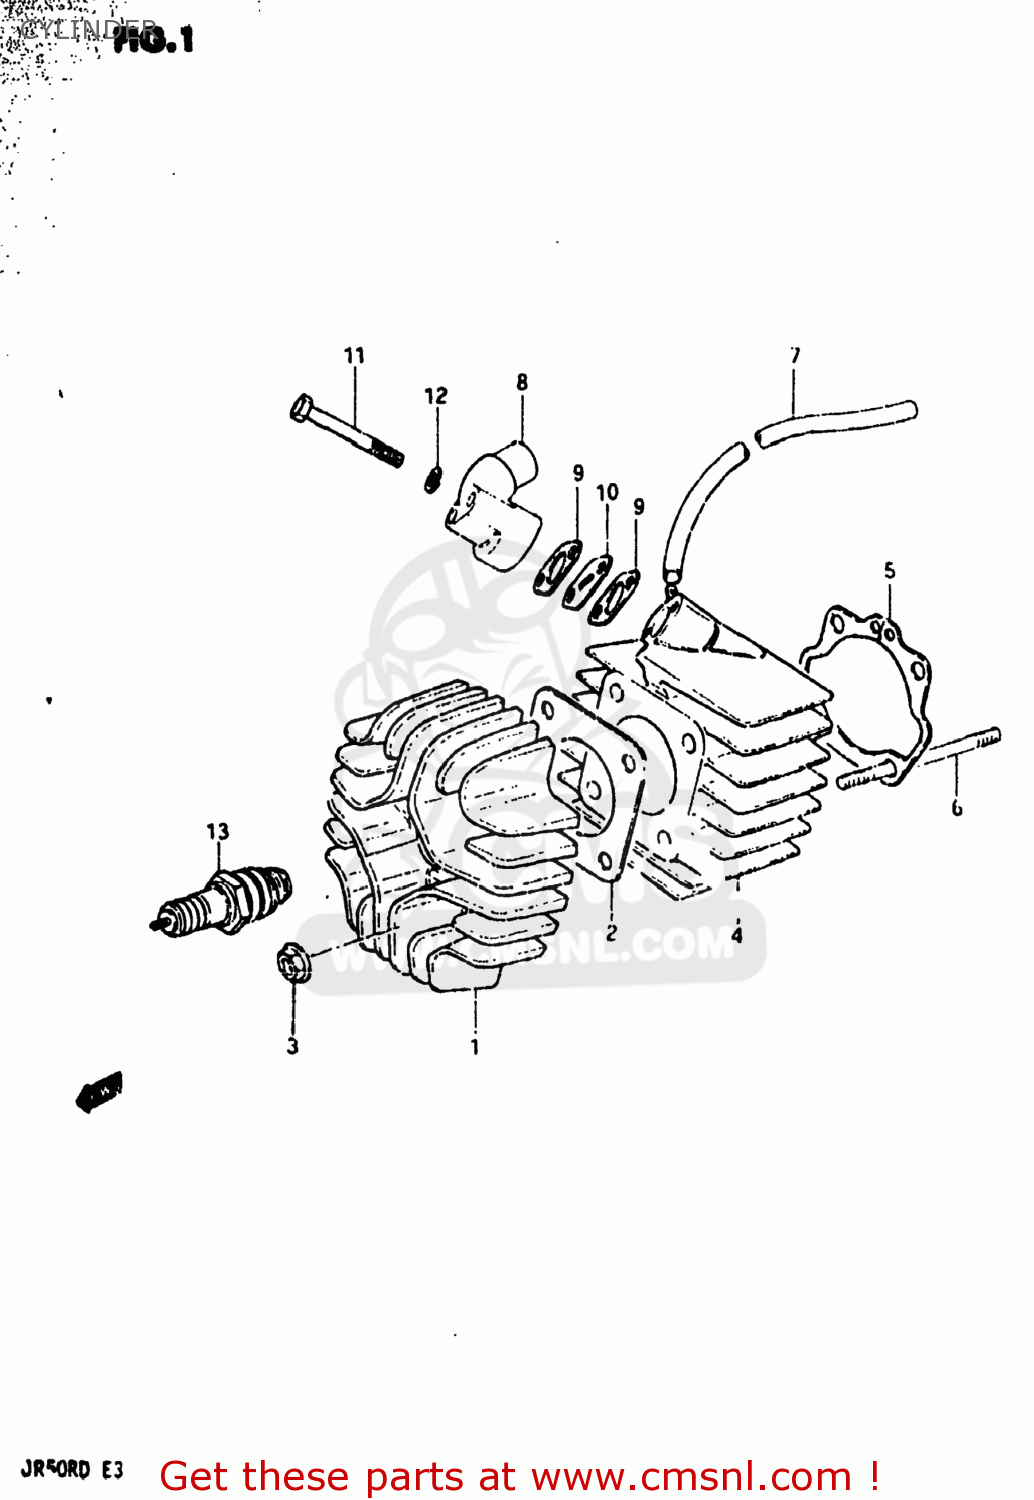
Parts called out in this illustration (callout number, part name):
1	HEAD,CYLINDER
2	GASKET,CYLINDER HEAD (NAS)
3	NUT
4	CYLINDER
5	GASKET,CYLINDER (MCA)
6	STUD BOLT
7	HOSE
8	PIPE,INTAKE
9	GASKET (NAS)
10	GASKET,CARBURETOR
11	BOLT
12	LOCK WASHER
13	SPARK PLUG
